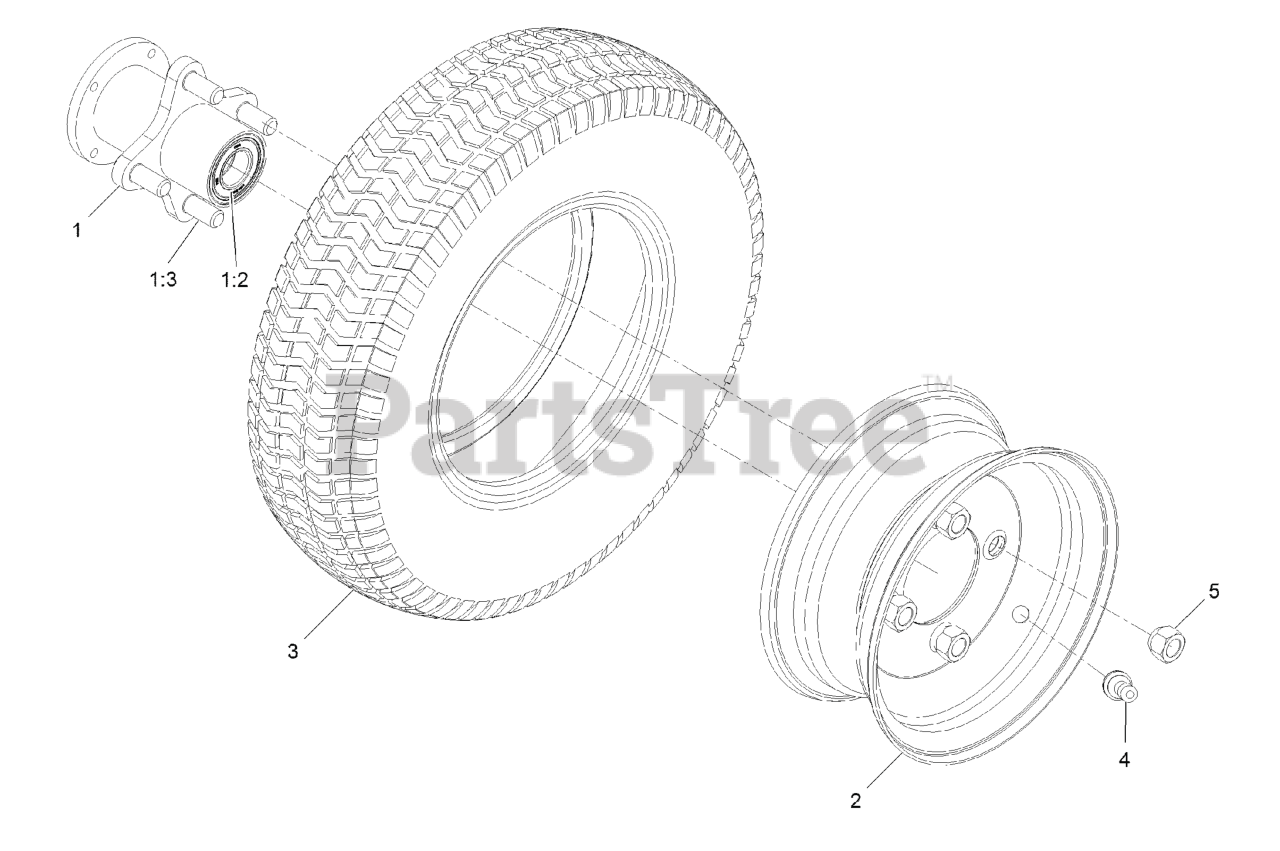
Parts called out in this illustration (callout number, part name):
1	Wheel Hub ASM
1:2	BEARING-BALL
1:3	STUD-TYPE, DRIVE
2	Rim
3	Tire
4	Stem-Valve
5	NUT-LUG
